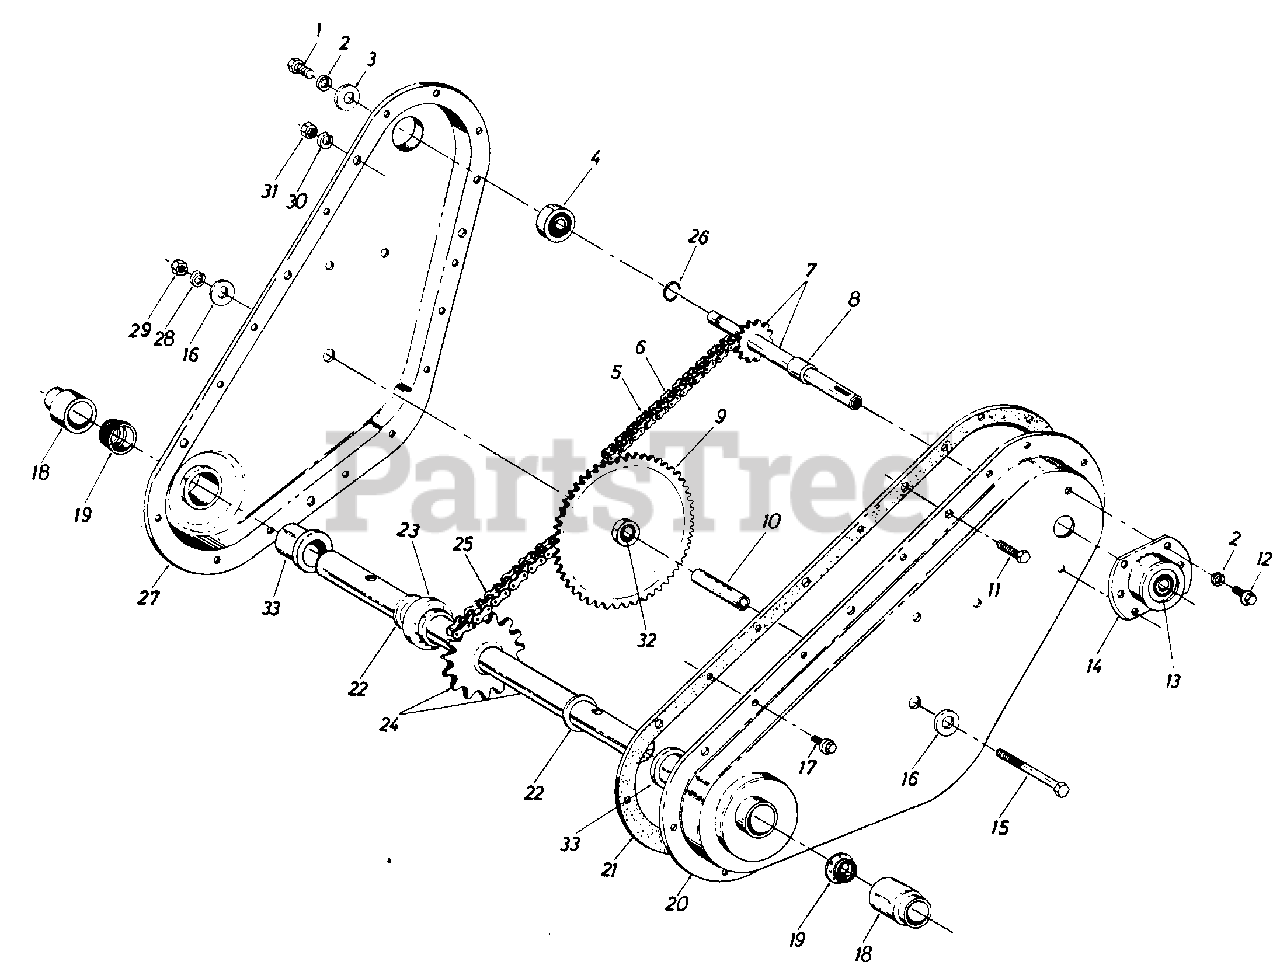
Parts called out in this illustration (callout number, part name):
1	Hex L-Bolt 1/4-28 x .625" Lg.
2	L-Wash. 1/4" I.D.
3	Fl-Wash. .25" I.D. x .93" O.D. x .125" Thk.
4	Bearing .62" I.D. x 1.38" O.D. x .437" Thk.
5	#35 Chain 3/8" Pitch x 52 Links Endless
6	Master Link
7	Input Shaft Assembly
8	Spacer
9	Sprocket Assembly
10	Sprocket Hub Tubing 3/8" I.D. x 5/8" O.D. x 1.9" Lg.
11	Hex Bolt 5/16-18 x .625" Lg.
12	Hex Wash. Hd. Self-Tap Scr. 1/4-20 x .50" Lg.
13	Bearing .625" I.D. x 1.38" O.D. x .437" Thk.
14	Bearing Housing
15	Hex Bolt 3/8-24 x 2.75" Lg.
16	Fl-Wash. 3/8" I.D. x 1.25" O.D. x .100" Thk.
17	Hex Wash. Hd. Self-Tap Scr. 1/4-20 x .50" Lg.
18	Dust Cap
22	Thrust Wash. 1.00" I.D. x .030" Thk.
23	Step Spacer
24	Tine Shaft Assembly
25	#50 Chain 518" Pitch x 46 Links Endless
26	Snap Ring 518" Dia. Shaft
29	Hex Nut 3/8-24 Thd.
30	L-Wash. 5/16" I.D.
31	Hex Nut 5/16-18 Thd.
32	Bearing
33	Bearing
